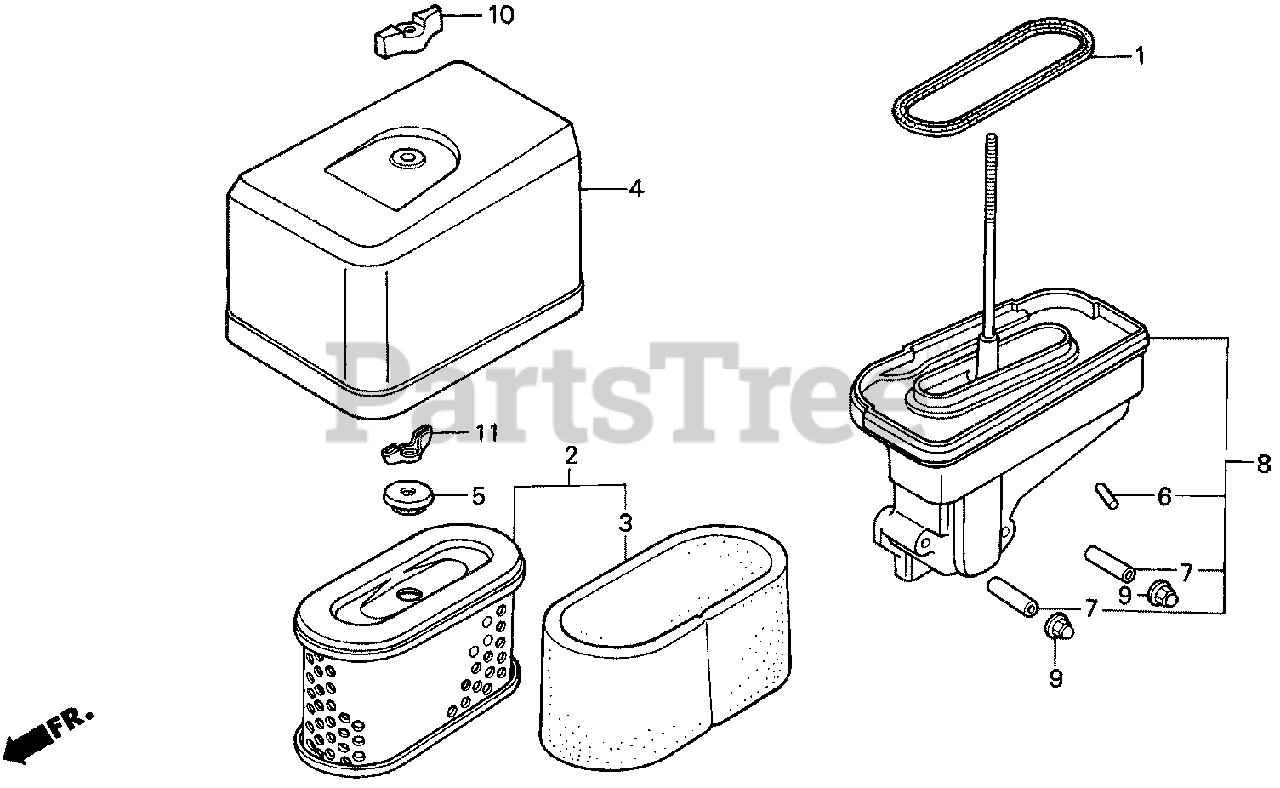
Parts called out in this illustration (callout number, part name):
1	GASKET, ELBOW
2	ELEMENT, AIR CLEANER
3	FILTER (OUTER)
4	COVER, AIR CLEANER (DUAL)
5	GROMMET, AIR CLEANER
6	COLLAR, AIR CLEANER
7	COLLAR, AIR CLEANER
8	ELBOW SET, AIR CLEANER
8	ELBOW, AIR CLEANER
9	NUT, CAP (6MM)
10	WINGNUT
11	WINGNUT, TOOL BOX SETTING
